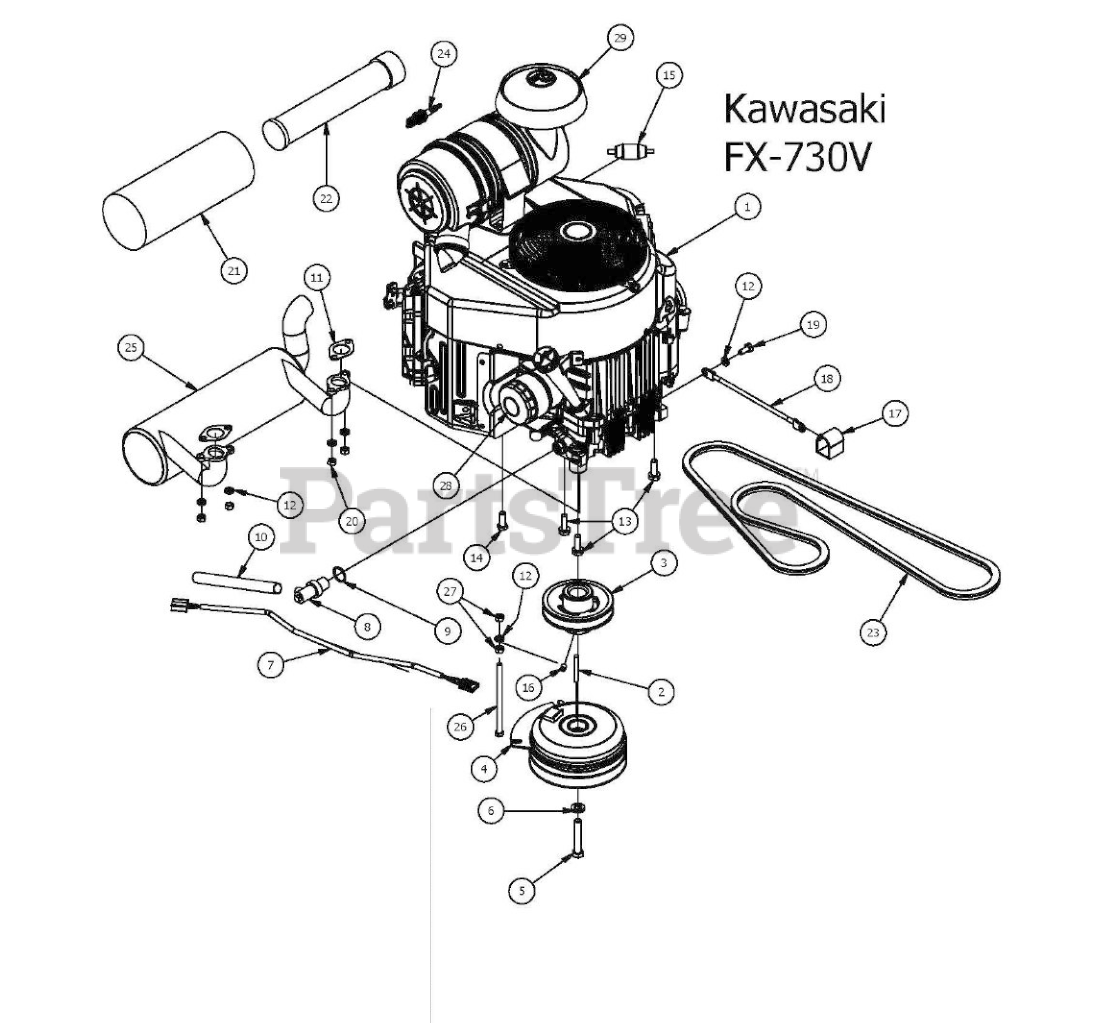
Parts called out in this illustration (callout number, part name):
2	1/4 x 2 Square key Stock
3	4 3/4 Motor Pulley
4	Clutch Assembly
5	7/16" x 21/2" Hex Bolt
6	7/16" Lock Washer
7	Clutch Pigtail
10	1/2 Clear Braded Hose Priced/Foot
11	Exhaust Gasket
12	5/16" Lock Washer
13	3/8 x 1 1/8 bolt
14	3/8" x 1" Hex Bolt
15	Universal Inline Fuel Filter
16	5/16 Set Screw
17	Black Boot For Ground Cable
18	Ground Cable
19	M8x1.20x20MM Hex head bolt
20	M8-1.25 Zinc Nut
21	Canister Air Filter- Outer
22	Canister Air Filter- Inner
24	Spark Plug Kawasaki
25	Exhaust-2015 Stand On
26	5/16-18 x 5-1/2 GR 5 Hex Bolt
28	Kawasaki Oil Filter
